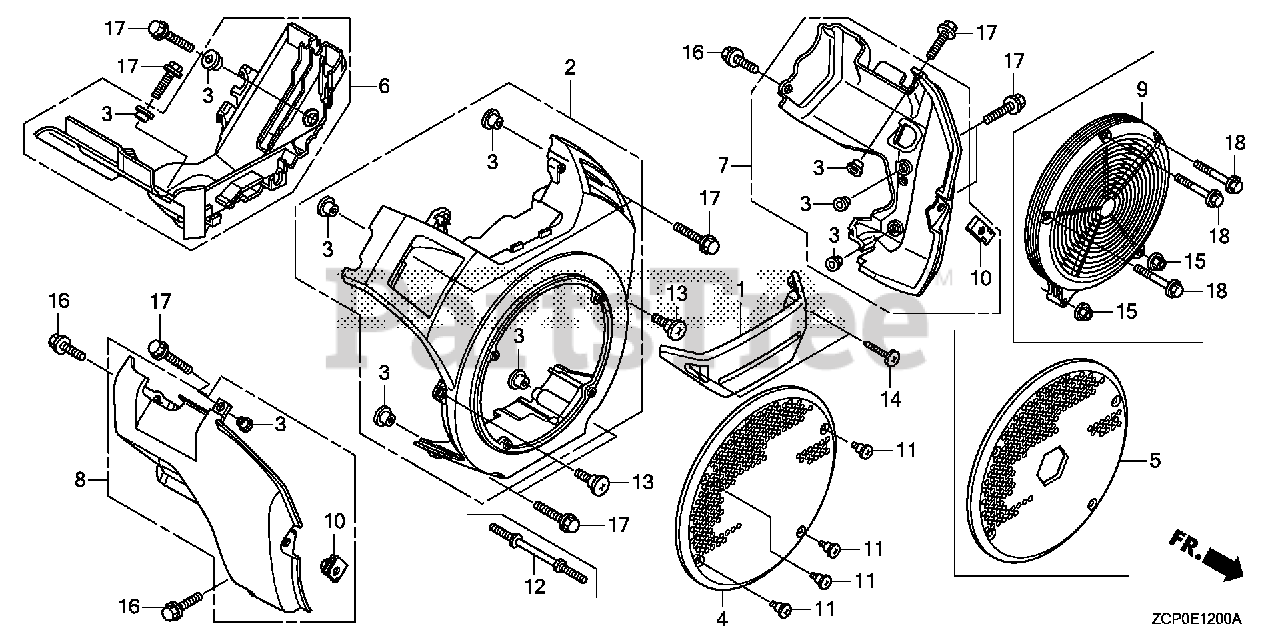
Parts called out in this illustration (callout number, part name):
1	COVER, FUEL PUMP
2	COVER, FAN *R280* (POWER RED)
2	COVER, FAN *NH1* (BLACK)
3	COLLAR, FAN COVER
5	PROTECTOR, FAN COVER (P.T.O.)
6	SHROUD (UPPER)
7	SHROUD, R. (LOWER)
8	SHROUD, L. (LOWER)
10	NUT, FENDER SETTING
11	SCREW, SPECIAL (4X10)
13	SCREW, SPECIAL (6X15)
14	SCREW, TAPPING (5X20)
16	BOLT, FLANGE (6X16)
17	BOLT, FLANGE (6X20)
